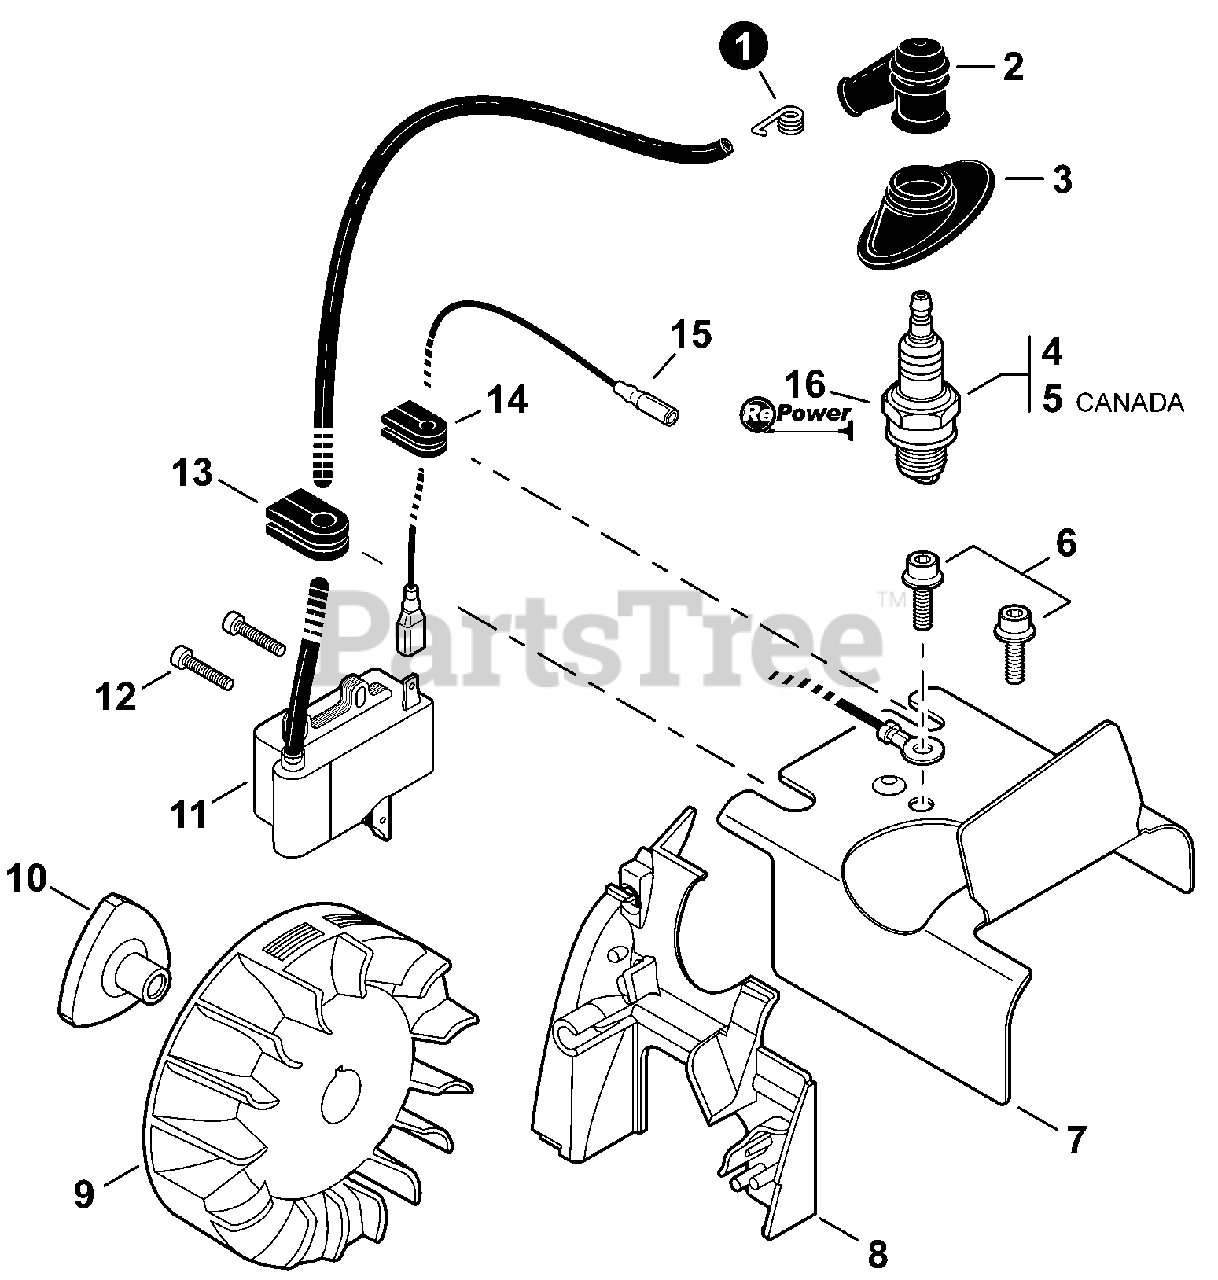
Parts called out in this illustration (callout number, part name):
1	TERMINAL, SPARK PLUG
2	CAP, SPARK PLUG
3	COVER, DUST
4	SPARK PLUG - BPM8Y
5	SPARK PLUG - BPMR8Y
6	BOLT 5×8
7	COVER, CYLINDER
8	COVER, CYLINDER - PLASTIC
9	FLYWHEEL
10	HUB, FAN
11	COIL, IGNITION
12	BOLT 4×20
15	LEAD - IGNITION
16	TUNE-UP KIT - REPOWER
